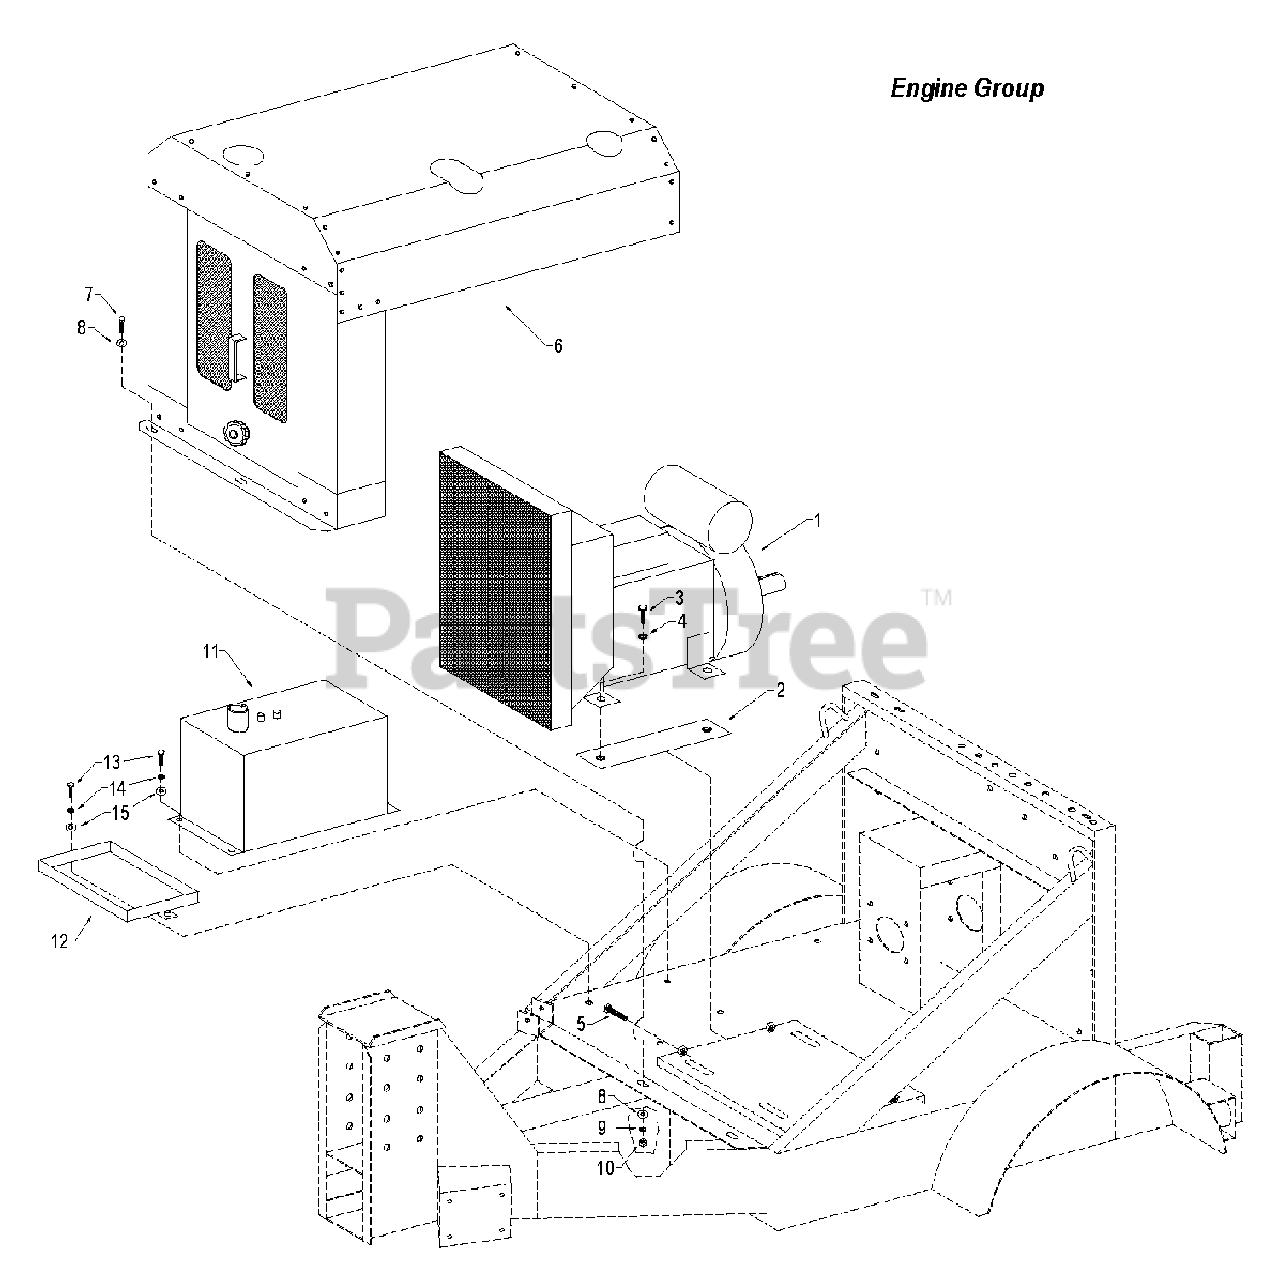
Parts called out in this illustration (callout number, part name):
1	* Engine – 49hp John Deere Diesel
2	Engine mount nut plate
3	Bolt, hex - 1/2-13 x 1-1/2"
4	Washer, lock - 1/2"
5	Bolt, Engine adjustment
6	Engine shroud - complete
7	Bolt, hex - 3/8-16 x 1"
8	Washer, flat – 3/8"
9	Washer, lock - 3/8"
10	Nut, hex - 3/8-16
11	Tank, fuel
12	Box, battery mounting
13	Bolt, hex - 3/8-16 x 1-1/4
14	Washer, lock - 3/8
15	Washer, flat - 3/8
